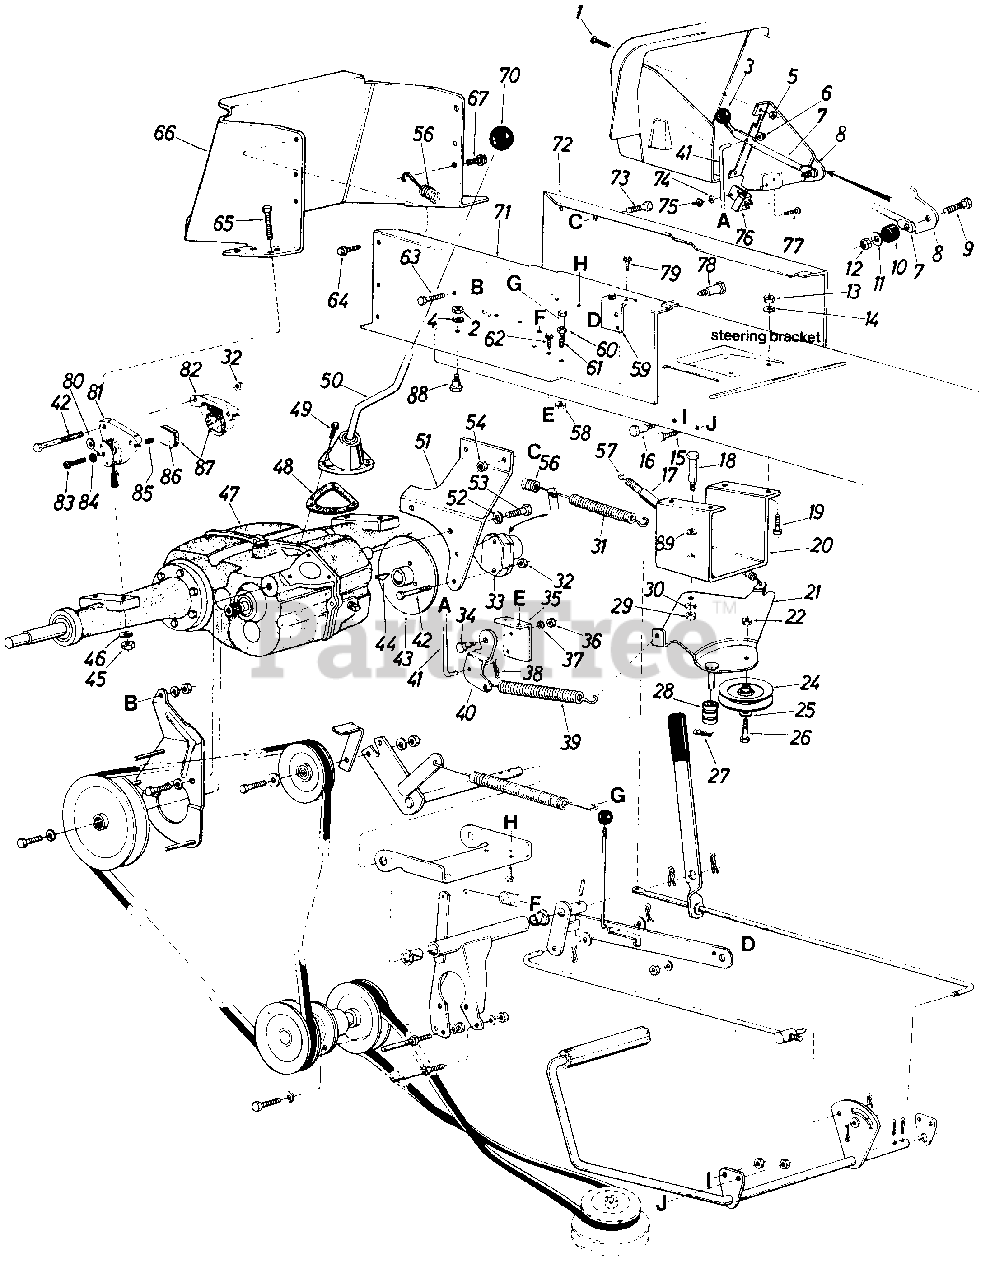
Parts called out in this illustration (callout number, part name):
1	Truss Mach. Scr. 1/4-20 x .50" Lg.
2	Hex Nut 1/4-20 Thd.
3	Knob Blade Clutch
4	L-Wash. 1/4 I.D.
5	Hex Sems Nut 1/4-20 Thd.
6	Push Cap 1/4" Rod
7	Blade Clutch Lever
8	Deck Clutch Control Brkt.
9	Hex Scr. 1/4-20 x 1.25" Lg.
10	Rubber Wash 330 I.D. x .87
11	Fl-Wash 1/4' I.D. x .75" O.D. x .057
12	Hex Cent. L-Nut 1/4-20 Thd.
13	Hex Nut 5/16-18 Thd.
14	L-Wash. 5/16" I.D.
15	Hex Bolt 3/8-16 x .62" Lg.
16	Shld. Bolt 1/2" Dia. x .335 Lg. 3/8-16
17	Convoluted Conduit .50 I.D. x 4" Lg.
18	Shld. Bolt 7/16 Dia. x .16" 5/1 6-1 8
19	Hex Bolt 5/16-18 x 1.00" Lg.
20	Idler Mtg. Brkt. Deck
21	Idler Brkt. Ass'y.
22	Hex L-Nut 3/8-16 Thd.
24	4" "V" Idler Pulley
25	Fl-Wash. 3/8" I.D.
26	Hex Bolt 3/8-16 x 1.25" Lg.
27	Hairpin Cotter 5/16" Rod
28	Spacer
29	Hex Nut 5/16-18 Thd.
30	L-Wash. 5/16" Scr.
31	Ext. Spring Brake Rod
32	Hex Cent. L-Nut 3/8-16 Thd.
33	Disc Brake Caliper Ass'y.
34	Shld. Scr. 7/16" Dia. x .16" Lg. 5/16-18
35	Parking Brake Cam Mtg. Brkt.
36	Hex Nut 5/16-18 Thd.
37	L-Wash. 5/16" I.D.
38	Hairpin Cotter 5/16" Dia.
39	Ext. Spring Deck Control
40	Deck Control Pivot Brkt.
41	Deck Control Rod
42	Hex Bolt 3/8-16 x 2.50" Lg.
43	Hub & Disc Ass'y.
44	Hi-Pro Key 3/16 x 314" Lg.
45	Hex Nut 3/8-16 Thd.
46	L-Wash. 3/8" I.D.
47	Transaxle
51	Transaxle Support
52	L-Wash. 3/8" Scr.
53	Hex Scr. 3/8-16 x .75" Lg.
54	Hex L-Nut 3/8-16 Thd.
56	Ext. Spring Brake Return
57	Ext. Spring Deck Idler Return
58	Hex L-Nut 5/16-18 Thd.
59	Parking Brake Cam Mtg. Brkt.
60	Hex Nut 5/16-18 Thd.
61	Hex Bolt 5/16-18 x 1.5" Lg.
62	Hex Thd. Rolling Scr. 1/4-20 x .50" Lg.
63	Hex Bolt 3/8-16 x .75" Lg.
64	Hex AB-Tap Scr. 5/16 x .75" Lg.
65	Hex Scr. 3/8-16 x 1.50" Lg.
66	Hitch Plate
67	Hex Thd. Rolling Scr. 5/16-24 x .75" Lg.
70	Knob Transaxle
71	Side Panel Upper Frame R.H.
72	Side Panel Upper Frame L.H.
73	Hex Bolt 3/8-16 x .75" Lg.
75	Hex Nut #10-24 Thd.
76	Safety Switch
77	Truss Mach. Scr. #10-24 x .50" Lg.
78	Shld. Bolt 7/16" Dia. x .16" Lg. 5/16-18
79	Hex Thd. Rolling Scr. 1/4-20 x .50" Lg.
81	Housing with Lever & Pin
83	Pin: Adjuster
84	Nut
85	Pin: Actuator
86	Backing Plate
87	Lining
88	Shld. Bolt .375" Dia. x .180" Lg. 1/4-20 Thd.
89	Wave Washer
